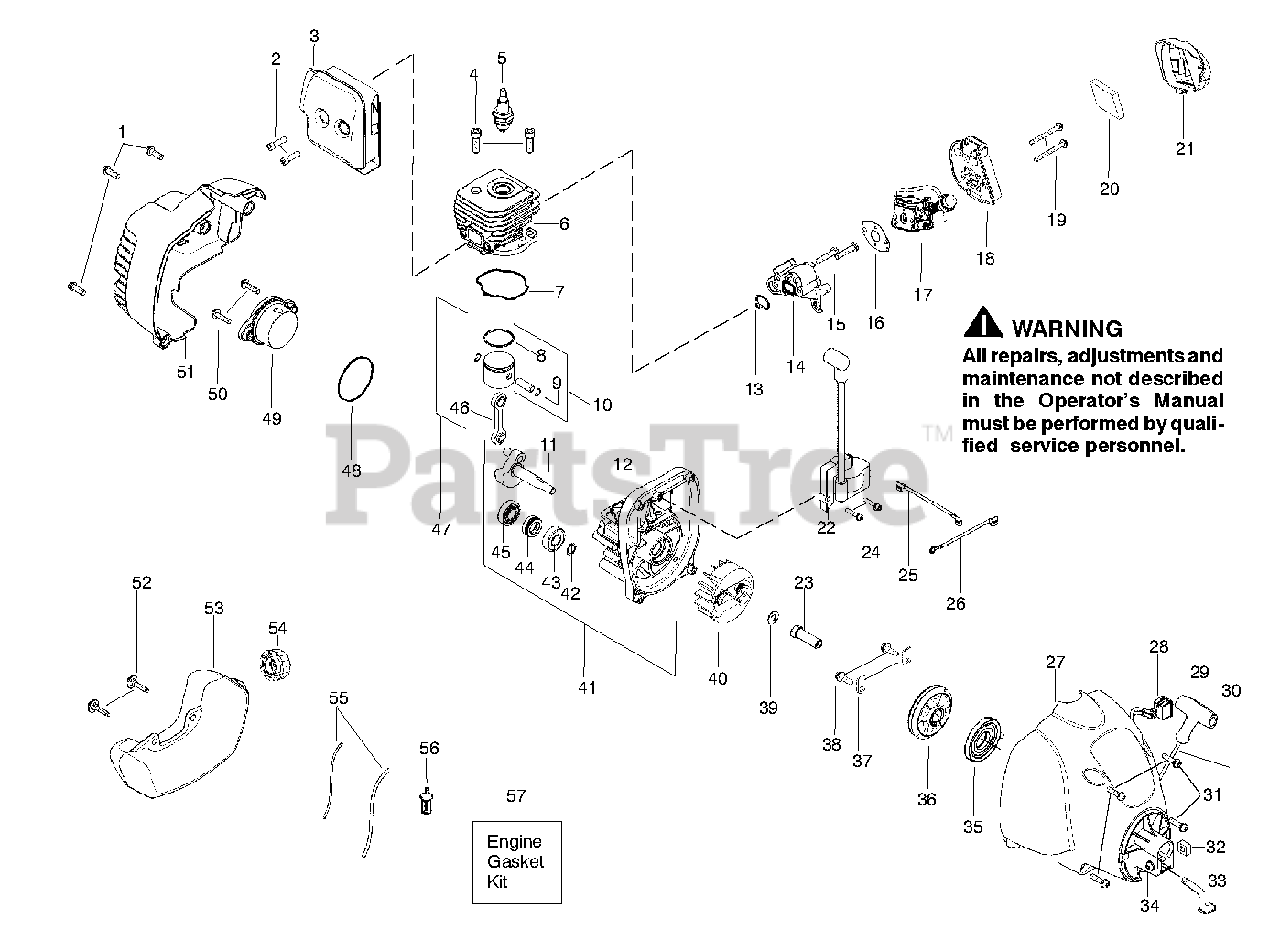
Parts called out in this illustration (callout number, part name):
2	BOLT MUFFLER
3	ASSY MUFFLER SHIELD
5	PLUG-SPARK (RCJ-6Y)
6	CYLINDER MACHINED 25CC LO
8	RING PISTON
9	WRIST PIN RET.
10	PISTON
11	ASSY CRANKSHAFT
12	ASSY CRANKCASE
14	ADAPTOR CARBURETOR
17	CARBURETOR ASSY
18	BASE AIRBOX
20	FOAM AIR FILTER
21	AIR BOX COVER
22	IGNITION MODULE
23	DRIVE-COUPLING
25	LEAD WIRE
26	SWITCH, GROUND WIRE
27	HOUSING FAN SPRING ASSIST
28	KIT SWITCH MOMENTARY
29	HANDLE-STARTER
30	KIT ROPE
32	NUT SQUARE
35	SPRING STARTER SA
36	KIT STARTER PULLEY
37	RETAINER
39	WASHER FLAT
40	FLYWHEEL
41	ASSEMBLY
42	RETAINING RING
43	OUTER BEARING
45	BEARING
46	KIT-CONN ROD ASSY
47	PISTON KIT
49	ASSY REAR PLUG
51	CYLINDER COVER
52	SCREW FUEL TANK RETAINER
53	FUEL TANK ASSY LOW PERM 188
54	FUEL CAP W/O RETAINER
56	FUEL PICK-UP ASSY
57	KIT GASKET 25CC
